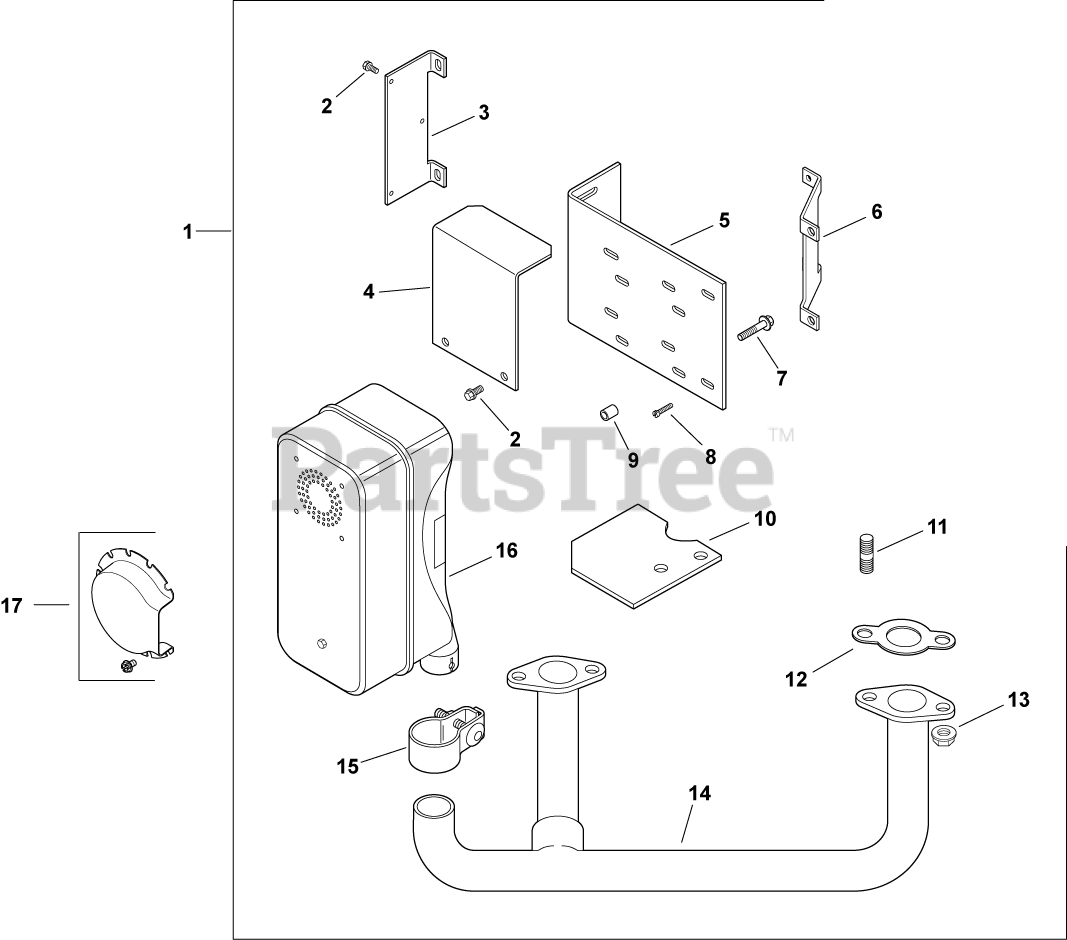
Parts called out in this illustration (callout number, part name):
1	KIT, MUFFLER/EXHAUST MNFLD
2	SCREW,FLG THD FRM M6X1.0X16-(#25086397S)
3	BRACKET, MUFFLER
4	DEFLECTOR, HEAT
5	BRACKET, MUFFLER
6	BRACKET, MUFFLER
7	SCREW, FLG M6X1.0X30
8	SCREW,WSH HD TAP 1/4-20X1 1/4"
10	DEFLECTOR, HEAT
11	STUD, EXHAUST-USE 25 072 24-S
12	GASKET, EXHAUST
13	NUT, FLG M8X1.25
14	MANIFOLD, EXHAUST SIDE 1
16	MUFFLER USE 24 068 126-S
17	KIT, MUFFLER DEFLECTOR-USE 24 755 168-S
